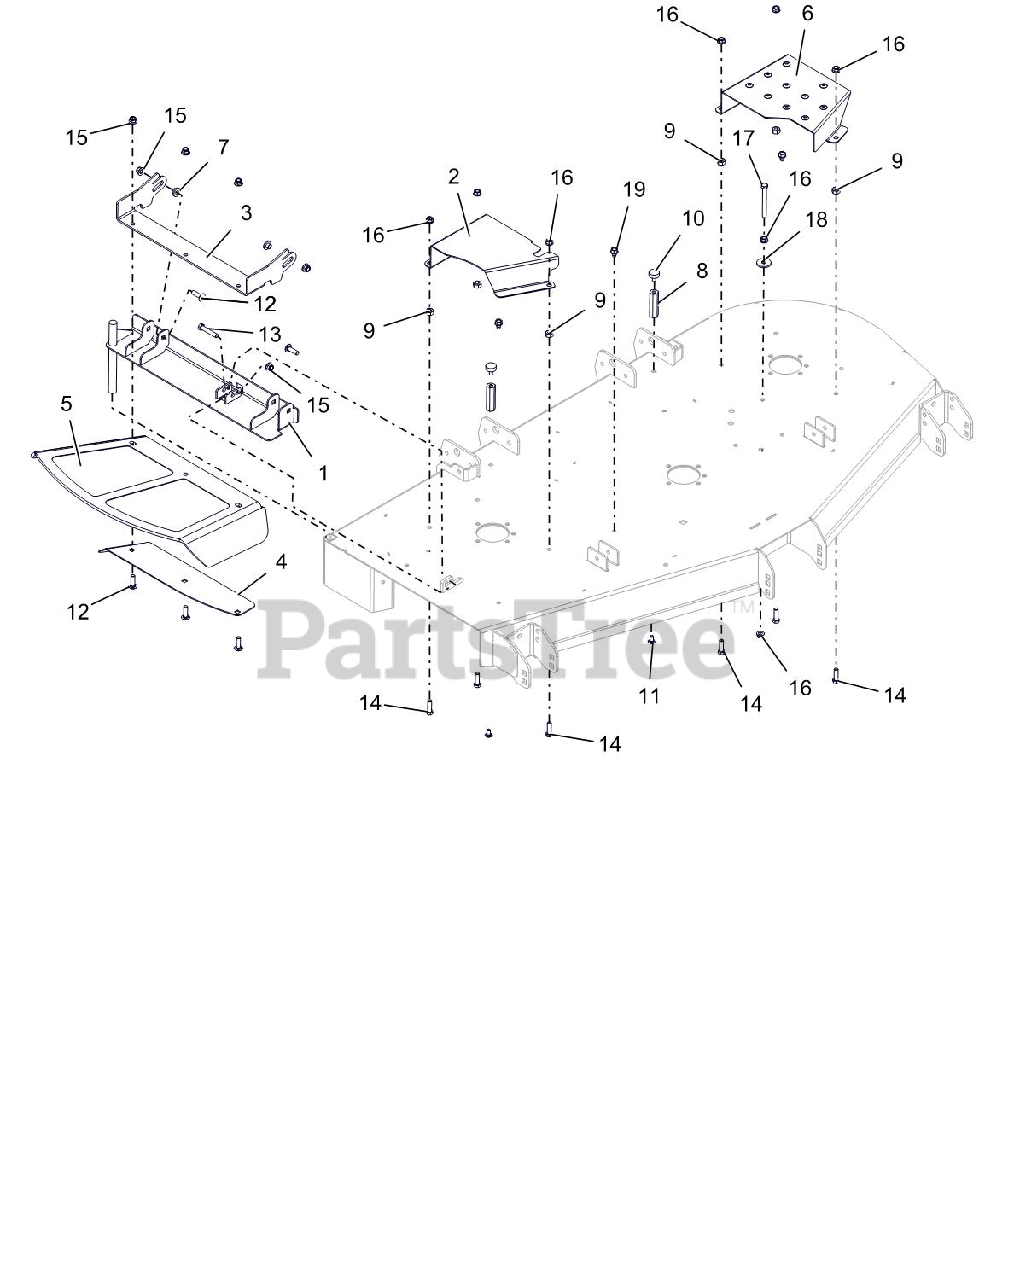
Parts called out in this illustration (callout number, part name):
1	48-60 DISCH CHT MTG WMT W/SAFE
2	GUARD,PRO-TURN DECK RH BELT-RD
3	48-60" CHUTE MTG BRKT - RED
4	48-60 DISCH CHUTE CLMP PLT-RED
5	CHUTE,48-60" FRMD RUBBER DISCH
6	GUARD,PRO-TURN DECK LH BELT-RD
7	BSHG-FLG .385X.500X.875X.406
8	NUT, COUPLING .31-18 2.75 LG
9	NUT-HEAVY HEX .38-16 YWZC
10	BUMPER, RUBBER
11	BLT-RDHDSQSHNK.31-18X.62 YZ-LK
12	@BLT-RHDSSQNK .38-16X1.25 G5YZ
13	@BLT-HEX .38-16X2.00 GR5 YWZC
14	@BLT-HEX .38-16X1.25 GR5 YWZC
15	@NUT-LK-NYL-FLG .38-16 YWZC
16	@NUT-SPNLK-FLG .375-16 YWZC
17	@BLT-HEX .38-16X3.50 GR5 YWZC
18	WSHR-FL-STL .406X1.375X.135 YZ
19	@SCR-TAP .38-16X.50 HWH TR YWZ
